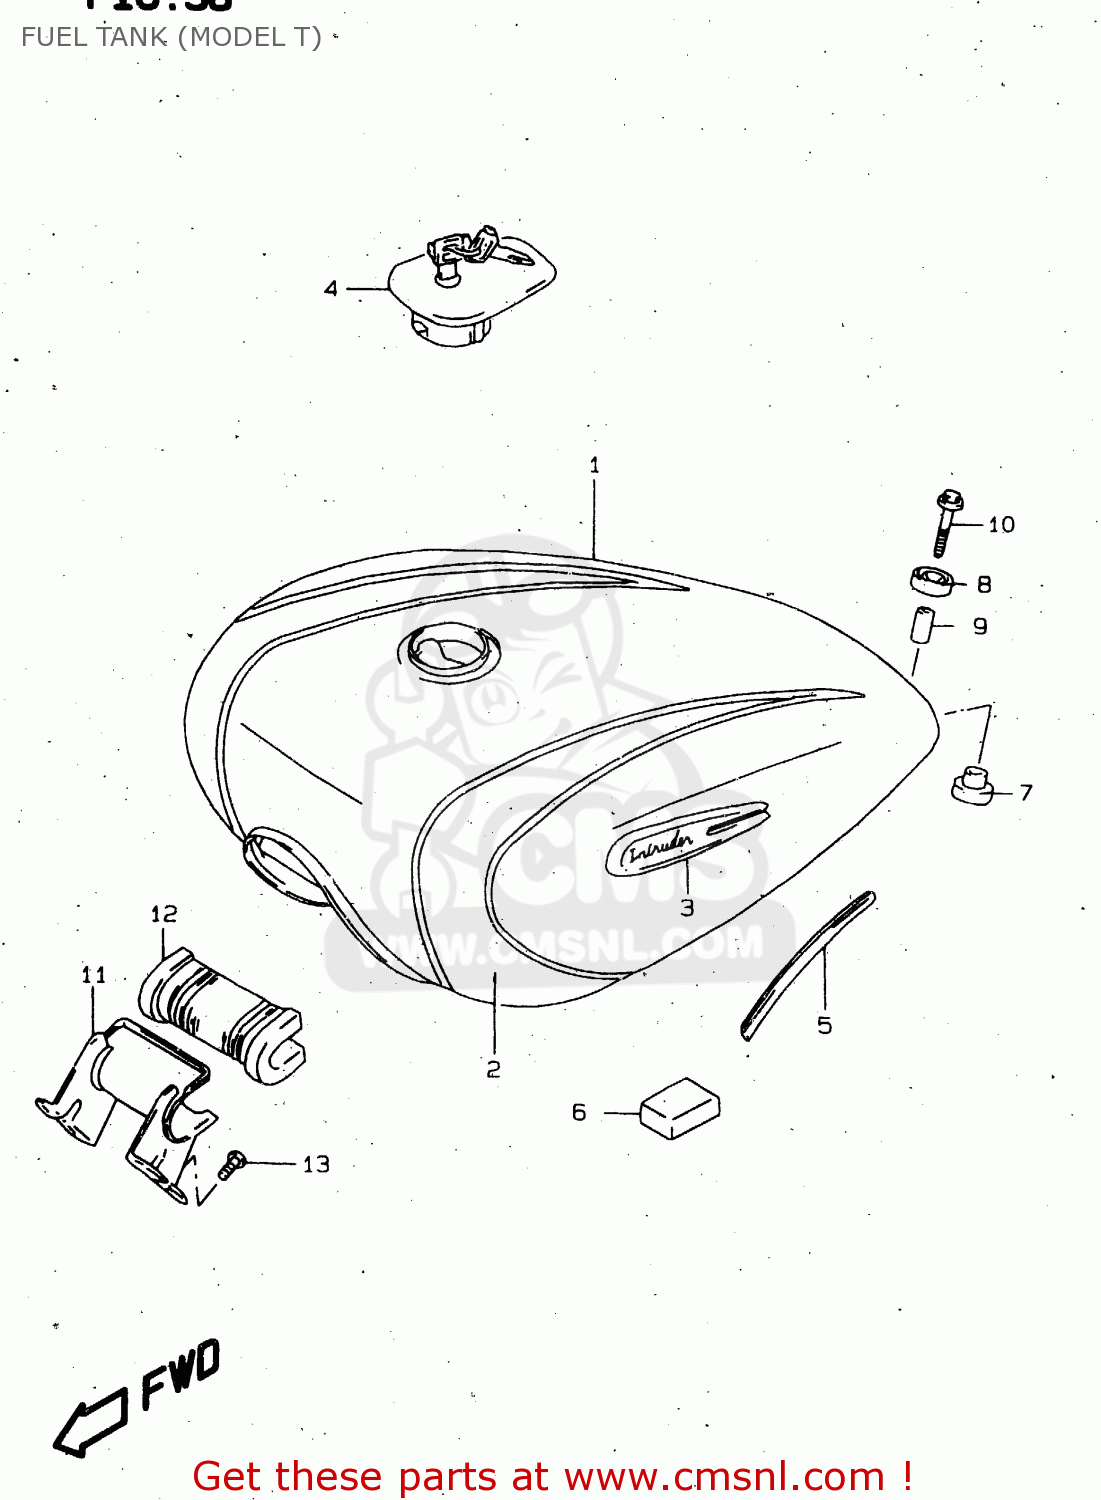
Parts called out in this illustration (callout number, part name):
1	TANK ASSY,FUEL
2	TAPE SET,FUEL TANK STRIPE
3	EMBLEM,FUEL TANK,R
4	CAP SET,FUEL TANK
5	MOLDING,FUEL TANK
6	CUSHION
7	CUSHION
8	CUSHION
9	SPACER
10	BOLT
11	BRACKET,TANK
12	CUSHION,FUEL TANK FR
13	SCREW
